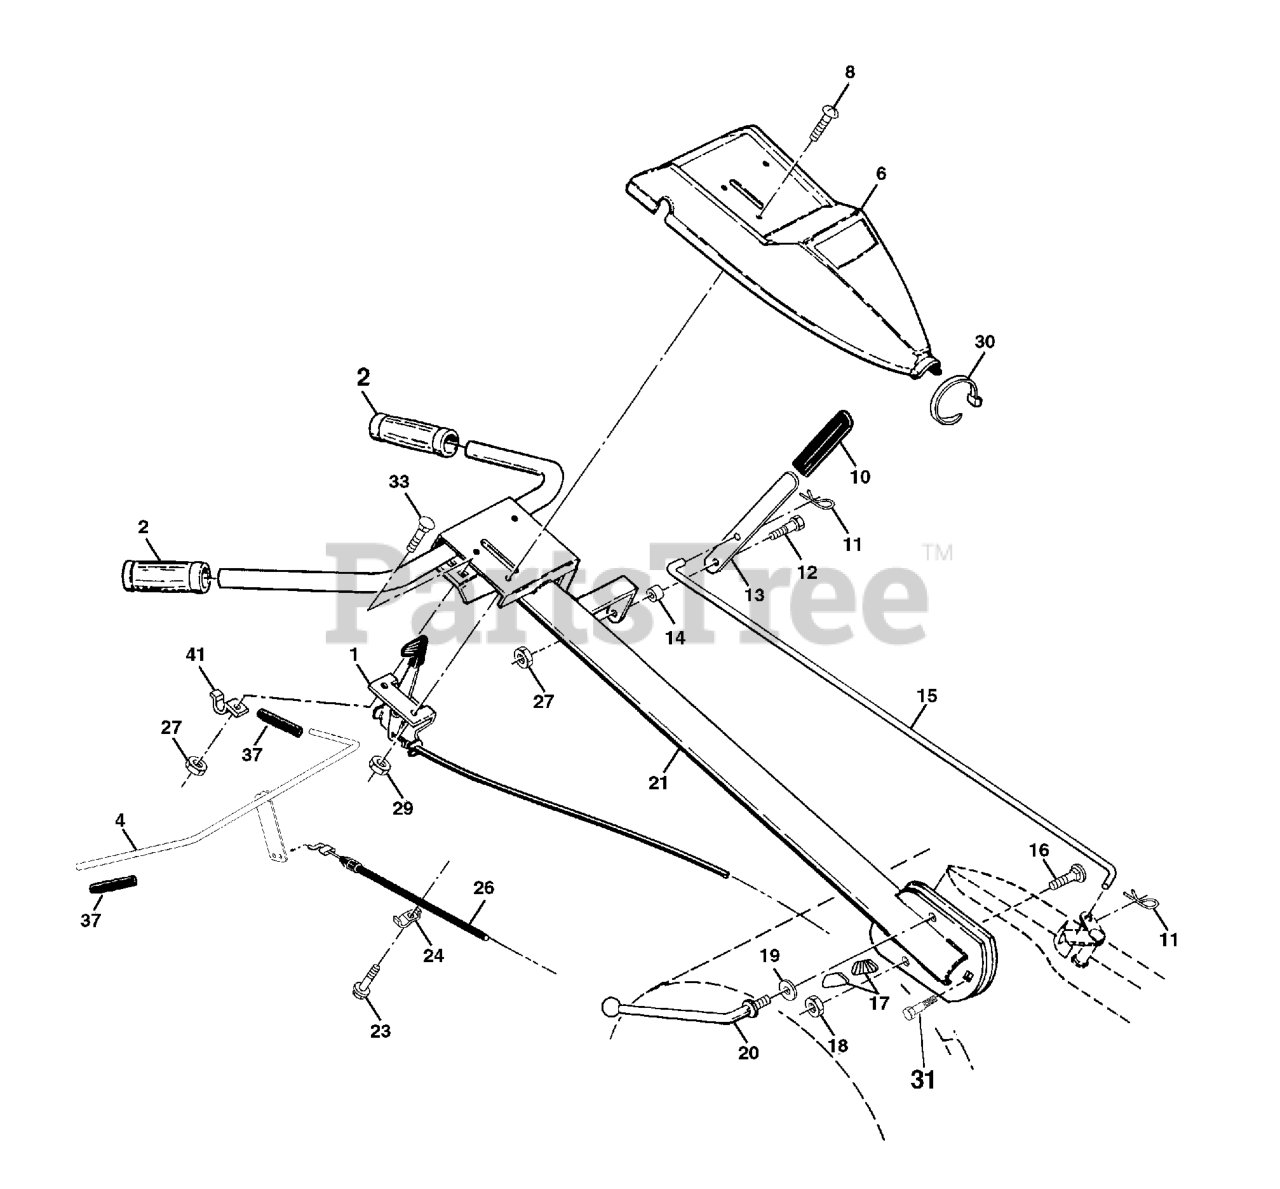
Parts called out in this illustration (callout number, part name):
1	THROTTLE CONTROL
2	KIT.GRIP.HANDLE.5.00.BLK.VINYL
4	CONTROL BAR ASSY
8	SCREW.PNHD.10-24
10	GRIP T
11	RETAINER M
12	SHOULDER BOLT ST
13	SHIFT HANDLE CRT
14	GROMMET.RUBBER.CRT.TILLER
15	SHIFT ROD CRT
16	BOLT D
17	LOCK.HANDLE.CRT
19	WASHER CRT
20	LEVER.LOCK.CRT
21	HANDLE ASSY
23	SCREW.HEX.WSH.SLT.#10-24X.50
24	CONDUIT.CLIP.PLATED
26	CABLE.CLUTCH
27	NUT T
29	NUT **
30	TIE CABLE CRT
31	BOLT.PIVOT
33	BOLT
37	GRIP BAR CRT(1)
41	CLAMP.BAR.CRT.BLACK
